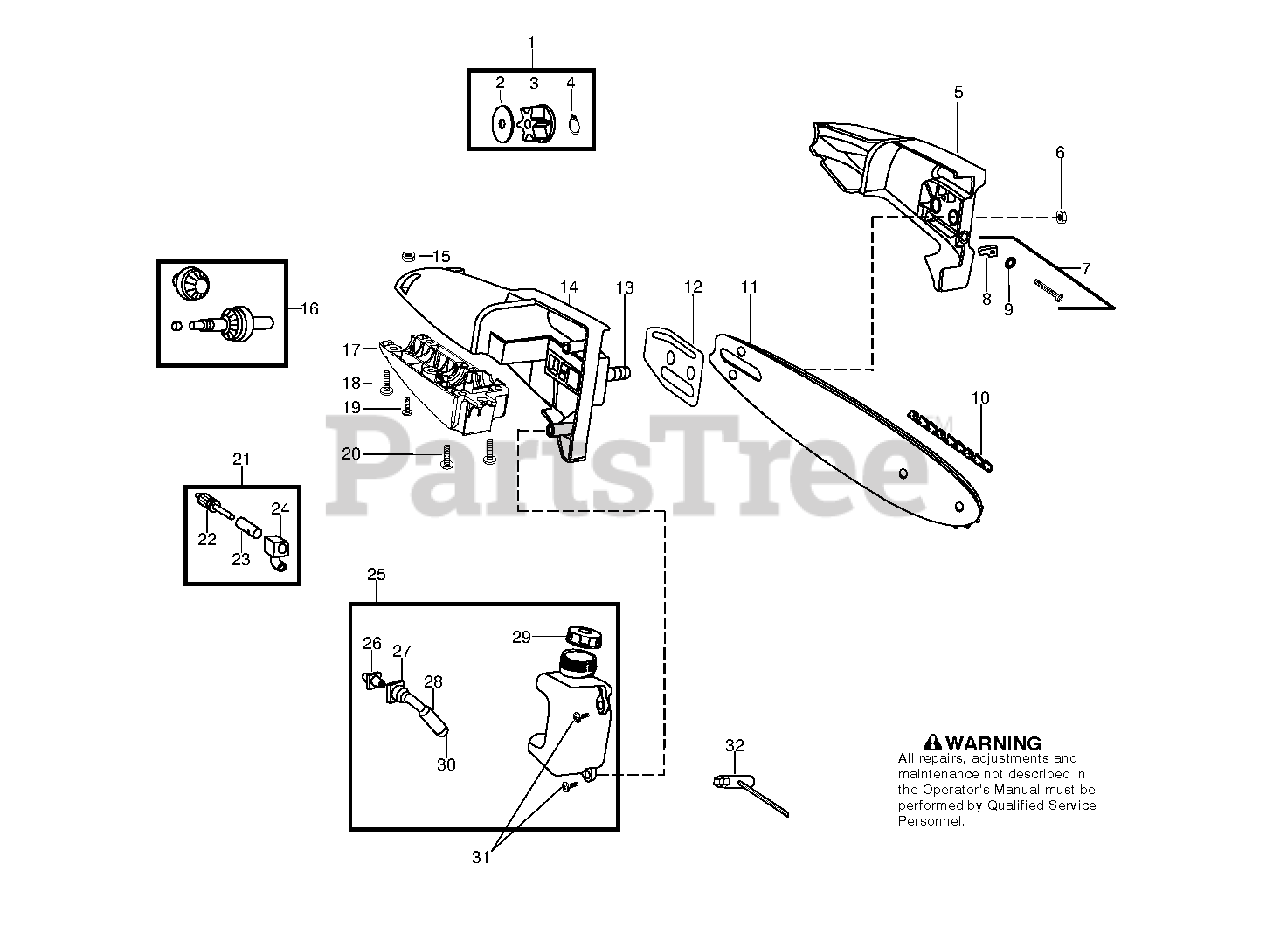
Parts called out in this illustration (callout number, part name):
1	SPROCKET
3	SPROCKET
4	RING SPROCKET RETAINER
5	BAR CLAMP ASSY
7	RETAINER
8	ADJUST PIN,BAR 36/41
9	RETAINER
10	ACCY UNI CHN 8" 90JG34DL 3/8
12	PAD BAR PLATE
14	GEAR HOUSING UPPER
16	KIT GEAR ASSY
17	GEAR HOUSING LOWER
18	SCR 10-24 MS LDK PAN PH
19	SCREW-10-14 X 1/2 PLASTITE
20	SCREW-10-14 X 13/16 (PL
21	OILER
22	ASSY GEAR PLUNGER
24	OIL BLOCK ASSY
25	ASSY OIL TANK PRUNER ATTACH
26	OIL PUMP FITTING
27	LINE OIL INTAKE
28	FILTER
29	CAP OIL
30	PLUG
32	WRENCH-BAR
